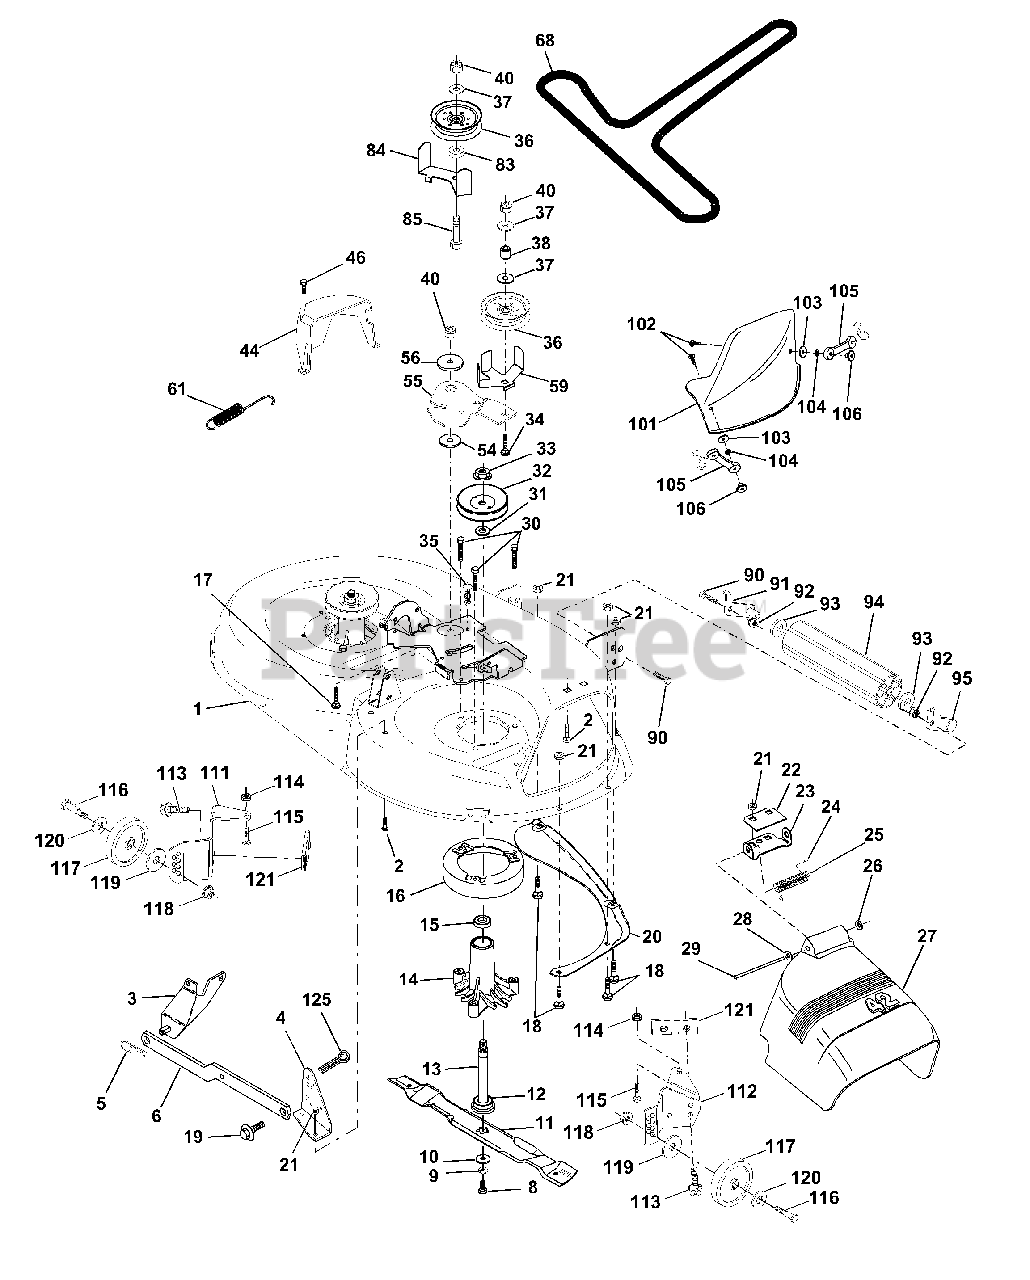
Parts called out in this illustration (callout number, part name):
1	Housing Asm Mower 42" 94 T-Path
2	Bolt Rdhd Sqnk 5/16-18unc X3/4
3	Bracket Asm Fr Sway Bar 38/42
4	Bracket Asm Deck 42"sway Bar
5	Retainer Spring
6	Arm Suspension Rear
8	Bolt 3/8-24x1 25 Gr8 Patched
9	Washer Lock Hvy 3/8 Unplated
10	Washer Hard Blade Mower Vented
11	Blade Mower Mulching 42"
12	Bearing Ball #6204 (Mandrel)
13	Shaft Asm W/lower Bearing
14	Housing Mandrel Vented(machd)
15	Bearing Ball Mandrel
16	Stripper Round Mower
17	Bolt Rdhd Sqnk 3/8-16 X 2-1/4
18	Bolt Carr 5/16-18 X 5/8
19	Bolt Shoulder
20	Baffle Vortex 42
21	Nut Crown Lock 5/16-18
22	Stiffener Bracket 42" deck
23	Bracket Deflector Mower 42"
24	Cap Sleeve 80x 112 Blk Mower
25	Spring Torsion Deflector 2 52
26	Nut Push Phos & Oil
27	Shield Deflector Mower 42" Blk
28	Washer 11/32 X 5/8 X 16 Ga
29	Rod Hinge 42" 6 75 Wlg
30	Screw Thdrol Hex Hd Zinc Mwr.
31	Washer Spacer Mower Vented
32	Pulley Mandrel 42"
33	Nut 9/16 top Lock Flng Cntr
34	Bolt RDHD 3/8-16 UNC x 2-3/4 Gr.5
35	Fastner Christmas Tree
36	Pulley Idler Flat 3 060
37	Washer 13/32 X 13/16 X 16 Ga
38	Spacer Spring Stop Idler
40	Nut Lock 3/8-16 Unc
44	Guard Mandrel LH Black
46	Screw Thdrol 1/4-20x5/8
54	Washer Hardened
55	Arm Idler 42" mower LT/YT
56	Spacer Retainer Pm Mower
59	Guard, Belt
61	Spring Ext. Elect
68	V-Belt Mower
83	Washer Sintered
84	Keeper Belt Idler Fixed
85	Bolt Carriage 3/8-16 x 2-1/4 Gr.5
90	Bolt Fin Hex 3/8-16unc X 1
91	Bracket Asm Noseroller LH
92	Nut Lock Hex w/ins. 3/8-16 UNC
93	Washer 17/32 X 7/8 X 16 Ga
94	Roller Nose 38 & 42
95	Bracket Asm Noseroller RH
101	Cover Mulching 42" Blk
102	Screw
103	Washer #10
104	Washer Lock #10
105	Latch Asm Bagger
106	Nut Weld .327/.304 #10-24
111	Bracket Wheel Gauge Lh 42" Deck
112	Bracket Gauge Wheel Rh 42" Deck
113	Screw Thdrol 5/16-18 x 3/4 TYT
114	Nut Keps 5/16 - 18 UNC
115	Bolt Carriage 5/16 - Unc x 1/2
116	Bolt Shld "A" 2.41 "B" 1.66
117	Wheel Gauge blk. 4.93
118	Nut Centerlock 3/8 - 16 UNC
119	Washer 3/8 x 7/8 x 14 Ga.
120	Washer 17/32 x 15/16 x 12 Ga.
125	Cotter Pin
